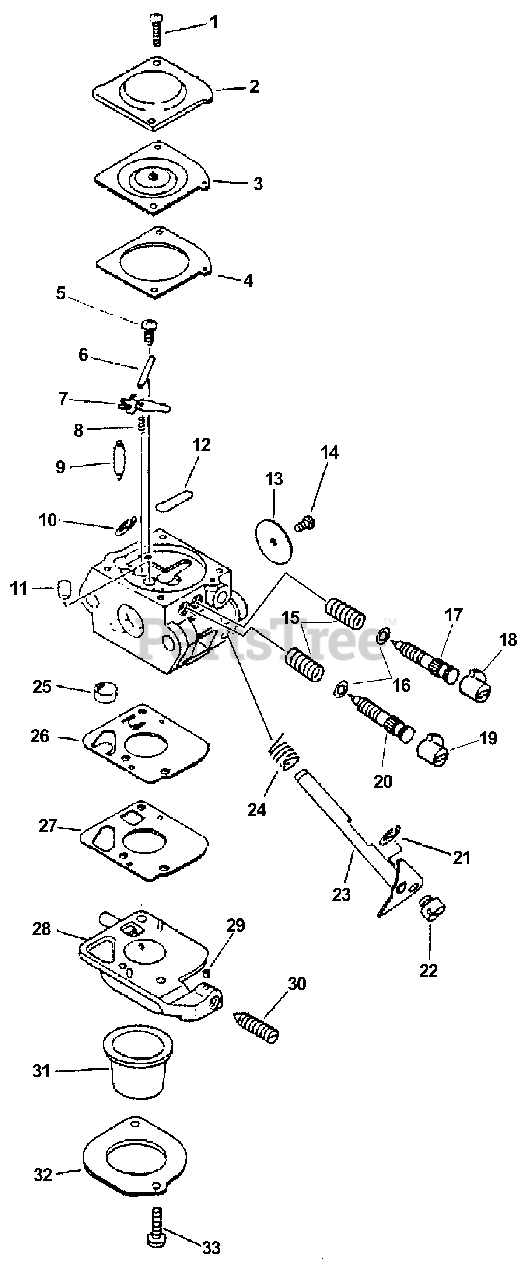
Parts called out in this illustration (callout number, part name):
2	COVER, METERING DIAPHRAGM
3	DIAPHRAGM
4	GASKET, DIAPHRAGM
6	PIN, METERING LEVER
7	LEVER, METERING
8	SPRING
9	VALVE, INLET NEEDLE
11	NOZZLE, CHECK VALVE
12	PLUG, WELCH
13	VALVE, THROTTLE
15	SPRING, NEEDLE
17	NEEDLE, IDLE
18	CAP, LIMITER - WHITE
19	CAP, LIMITER - RED
20	NEEDLE, HIGH SPEED
23	SHAFT, THROTTLE
24	SPRING, THROTTLE RETURN
25	STRAINER
26	DIAPHRAGM, PUMP
27	GASKET, PUMP
28	BODY ASSY, PURGE
29	PIECE, FRICTION
30	SCREW, IDLE ADJUST
31	BULB, PURGE
32	RETAINER
